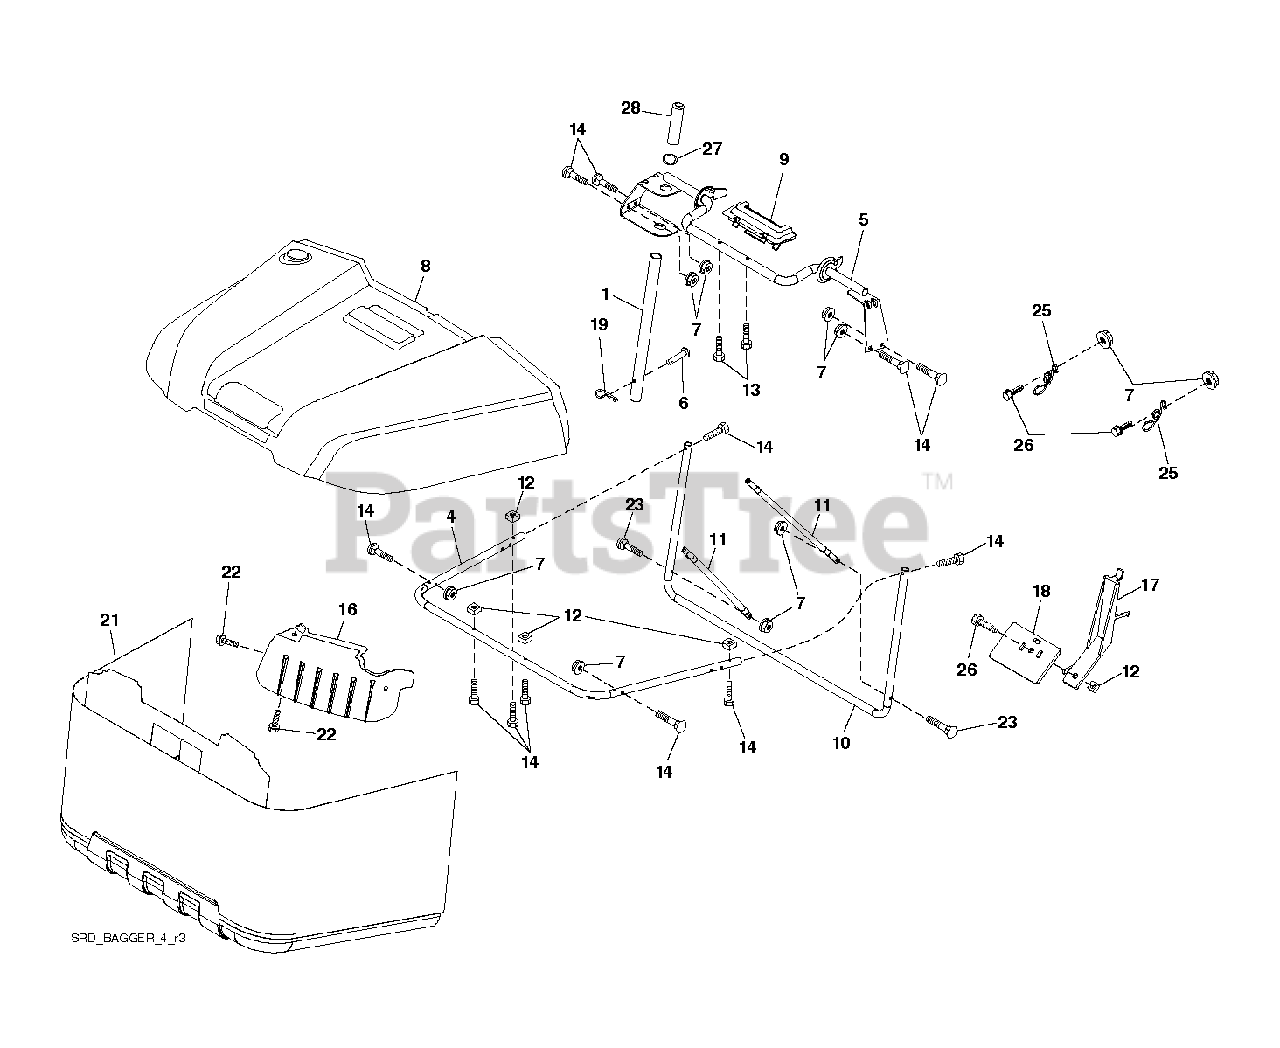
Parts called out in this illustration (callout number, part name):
1	TUBE.PNT.HDL.BAGGER.
5	FRAME.ASM.TOP.BAGGER.SRD
6	RIVET,DRILLED
7	NUT T
8	COVER.BAGGER.SRD.BLACK
9	INSERT.HANDLE.BAGGER.(2 2)
10	FRAME.FRONT.SRD.BAGGER
11	TUBING.BRACE.BAGGER.SRD.BLACK
12	NUT.SQUARE.1/4
13	SCREW.1/4X1.150.HXWSH
14	BOLT.SHOULDER.HX.WSH.1/4X1.150
16	DEFLECTOR.BAGGER.SRD
17	Bagger Lever, Full SRD Black
18	PADDLE.BAGGER.FULL.SRD.BLACK
19	PIN.COTTER.5/16.BOW TI
22	SCREW.HI-LO.CONSOLE
25	SPRING.LATCH.BAGGER.SRD
26	SCREW HEX CRT
27	GROMMET.RUBBER.SRD
28	GRIP.HANDLE.BLACK
